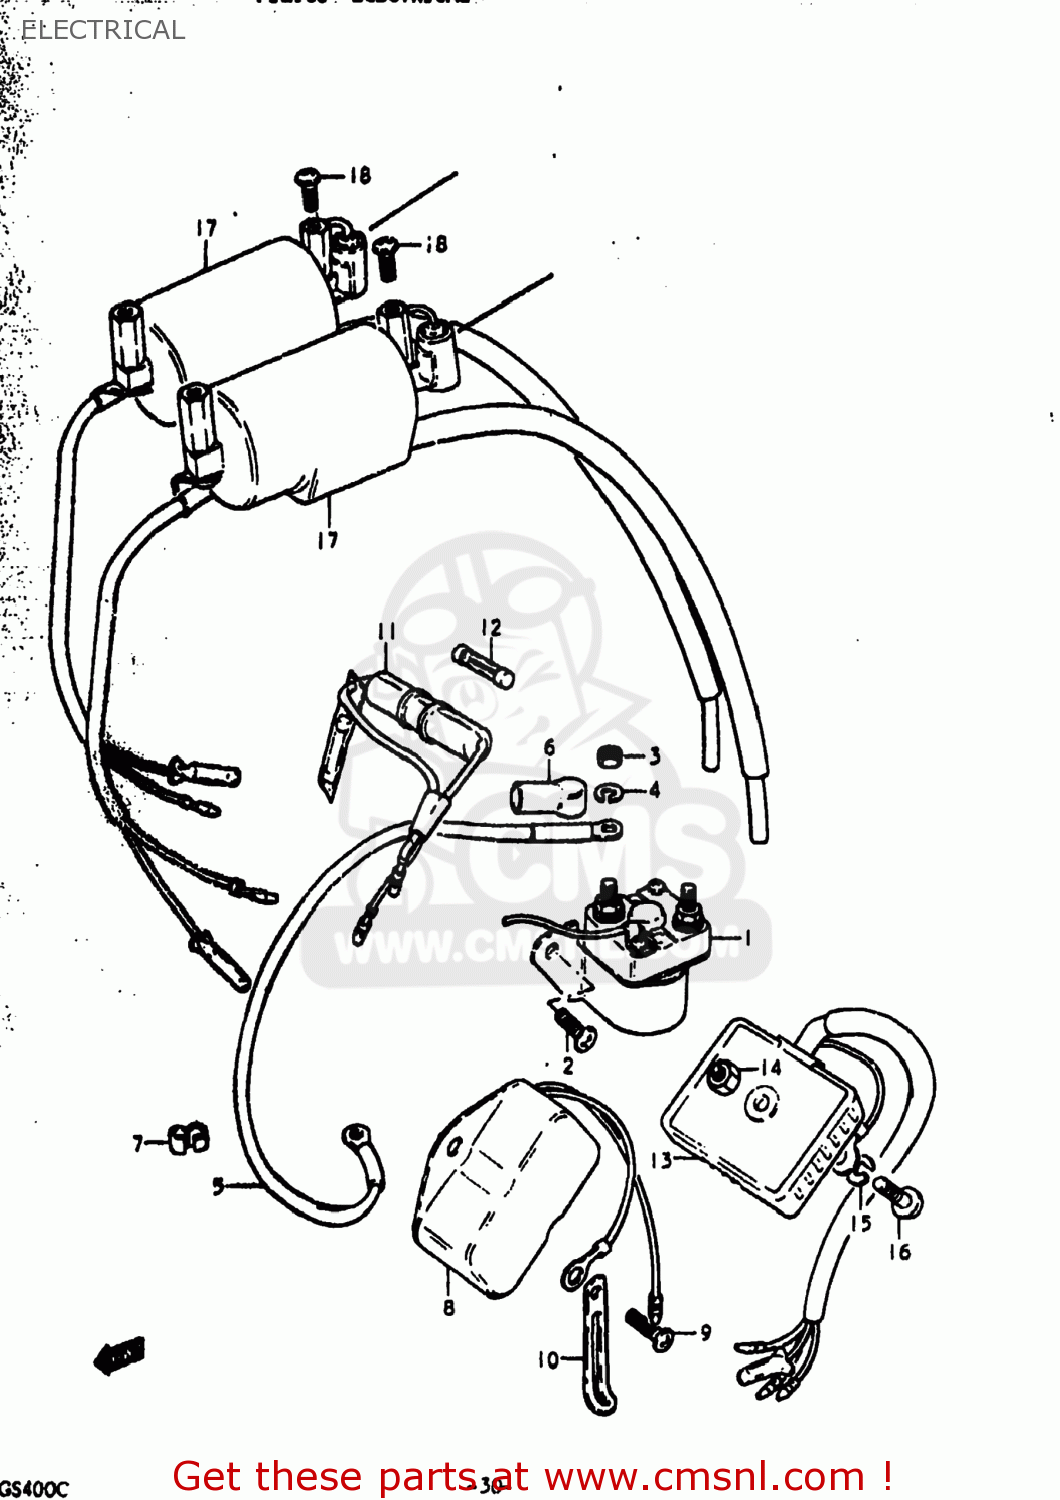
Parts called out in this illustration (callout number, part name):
1	RELAY ASSY,STARTING MOTOR
2	SCREW
3	NUT 6MM
4	LOCK WASHER
5	WIRE,STARTER MOTOR LEAD
6	CAP,STARTER RELAY
7	CLIP
8	REGULATOR ASSY,VOLTAGE
9	SCREW
10	CLAMP L:35
11	BOX ASSEMBLY,FUSE
12	FUSE(15A)
13	RECTIFIER ASSY
14	NUT
15	LOCK WASHER
16	SCREW
17	COIL ASSEMBLY,IGNITION
18	SCREW
19	CONDENSER
